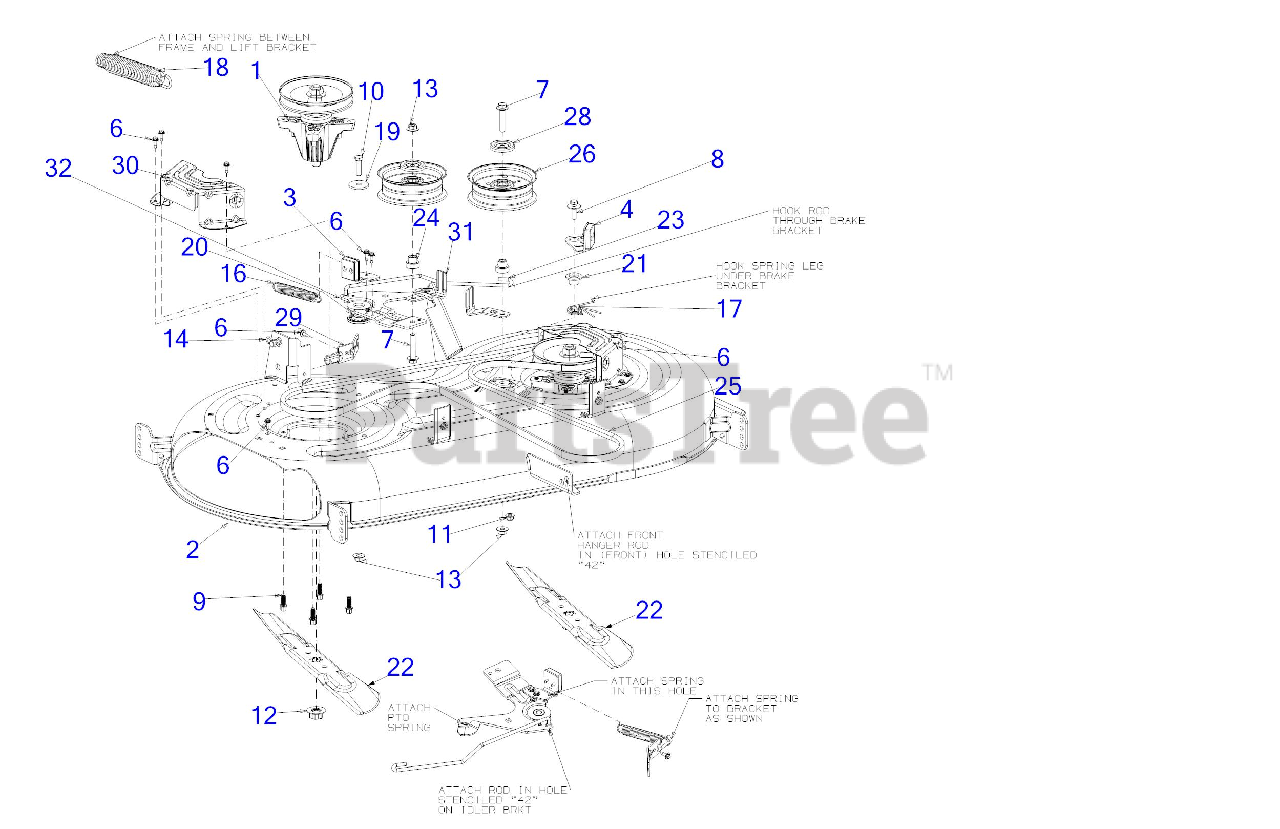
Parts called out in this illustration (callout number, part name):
1	PULLEY & SPINDLE ASSEMBLY
3	DECK BRAKE ASSEMBLY (RH)
4	DECK BRAKE ASSEMBLY (RH)
6	SCREW M6-1 x .625
7	SCREW 3/8-16 x 2.0
8	SCREW 5/16-18X1.25 GR 5
9	SCREW 5/16-18 X .875
10	SCREW 3/8-16 x 1.25 GR5
11	FLANGE LOCK NUT 5/16-18
13	FLANGE LOCK NUT
14	BOW TIE COTTER PIN
16	EXTENSION SPRING
17	TORSION SPRING
18	LIFT ASSIST SPRING
19	FLAT WASHER .390x1.500x.134
20	SHOULDER SPACER
21	DOUBLE SHOULDER SPACER .750 X .135
22	21.23" BLADE (2N1)
23	DECK BRAKE ROD
24	SHOULDER SPACER
25	V-BELT A SEC x 99.75
26	IDLER PULLEY 4.50" DIA
28	IDLER PULLEY CAP
29	ENGAGEMENT CABLE BRACKET
